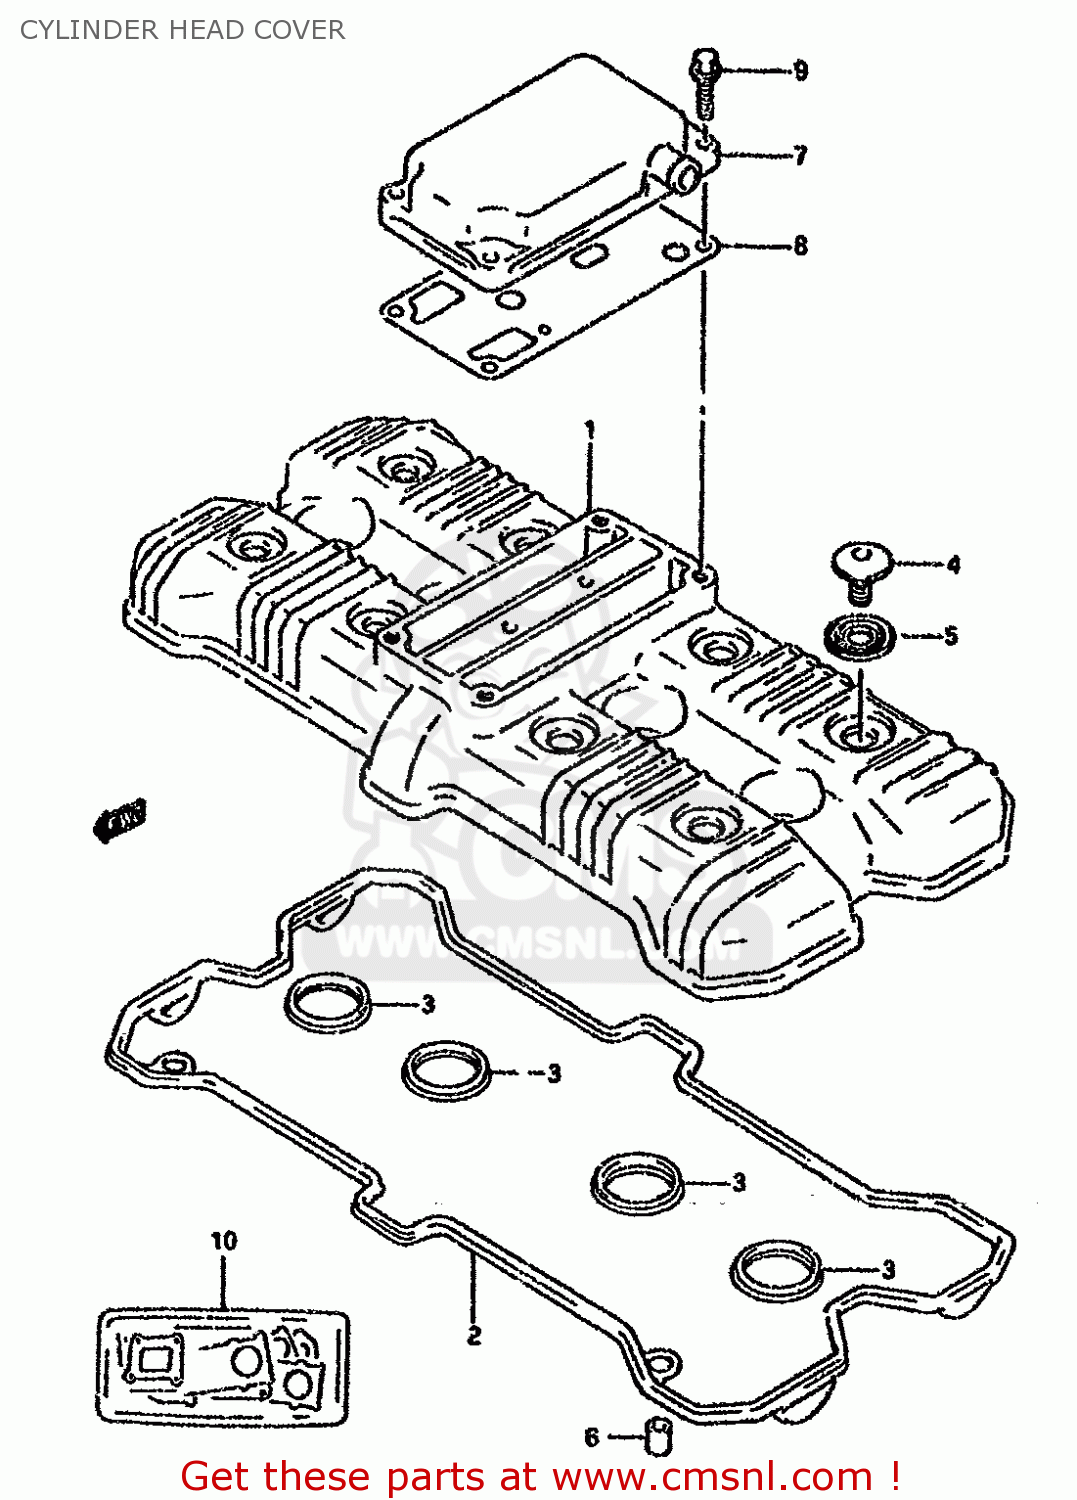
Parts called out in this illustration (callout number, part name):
1	COVER,CYLINDER HEAD
2	GASKET,CYL HEAD COVER NO.1
3	GASKET,CYL HEAD COVER NO.2
4	BOLT(7X17.5)
5	WASHER(10.6X25.5X2.3)
6	PIN(6.2X8X11)
7	COVER,BREATHER
8	GASKET,BREATHER COVER
9	BOLT
10	GASKET SET (NAS)
